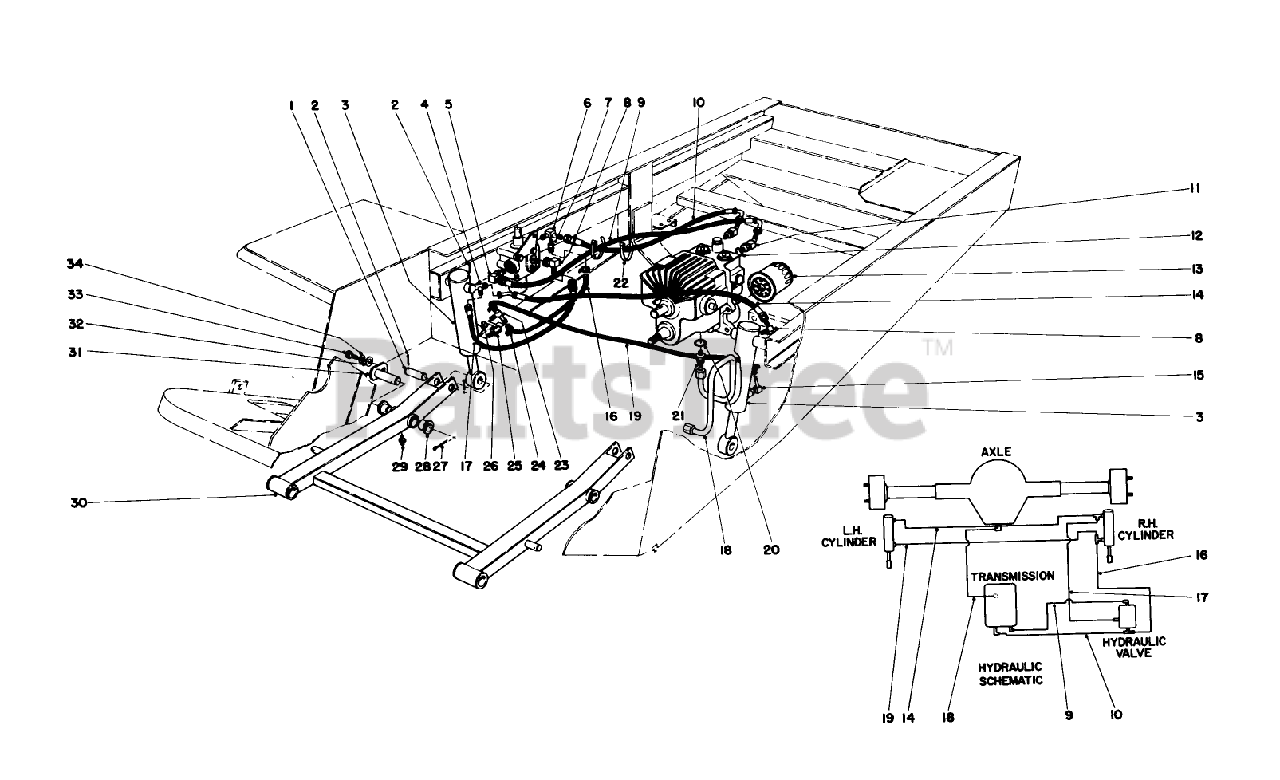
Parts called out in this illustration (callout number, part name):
1	Pin Cylinder
2	PIN-COTTER
3	Lift Cylinder
4	FITTING-TEE, ADJ.
5	FITTING-ELBOW, 90 DEG
6	Fitting Assembly
7	FITTING-STRAIGHT
8	FITTING-ELBOW, 90
9	Hose Transmission to Valve Pressure
10	Hose Transmission to Valve Low Pressure
11	FITTING-STRAIGHT
12	O-RING
13	FILTER-OIL, TRANSMISSION
14	RH CYL HOSE
15	STEM-HOSE
17	RH HOSE
18	HYORAULIC TUBE
19	HOSE-FUEL
20	O-RING
21	FITTING-STRAIGHT
22	TIE-CABLE
23	MALE TEE FITTING
24	CLAMP-HOSE
25	CONN FITTING
26	O-RING
27	PIN-COTTER
28	7/8 ID X 1.128 X 7/8 LG BSHG
29	GREASE FITTING
30	Lift Arm (Incl. Ref. #28-29)
31	Pivot Pin
32	WASHER-FLAT
33	SCREW-HH
34	WASHER-LOCK
